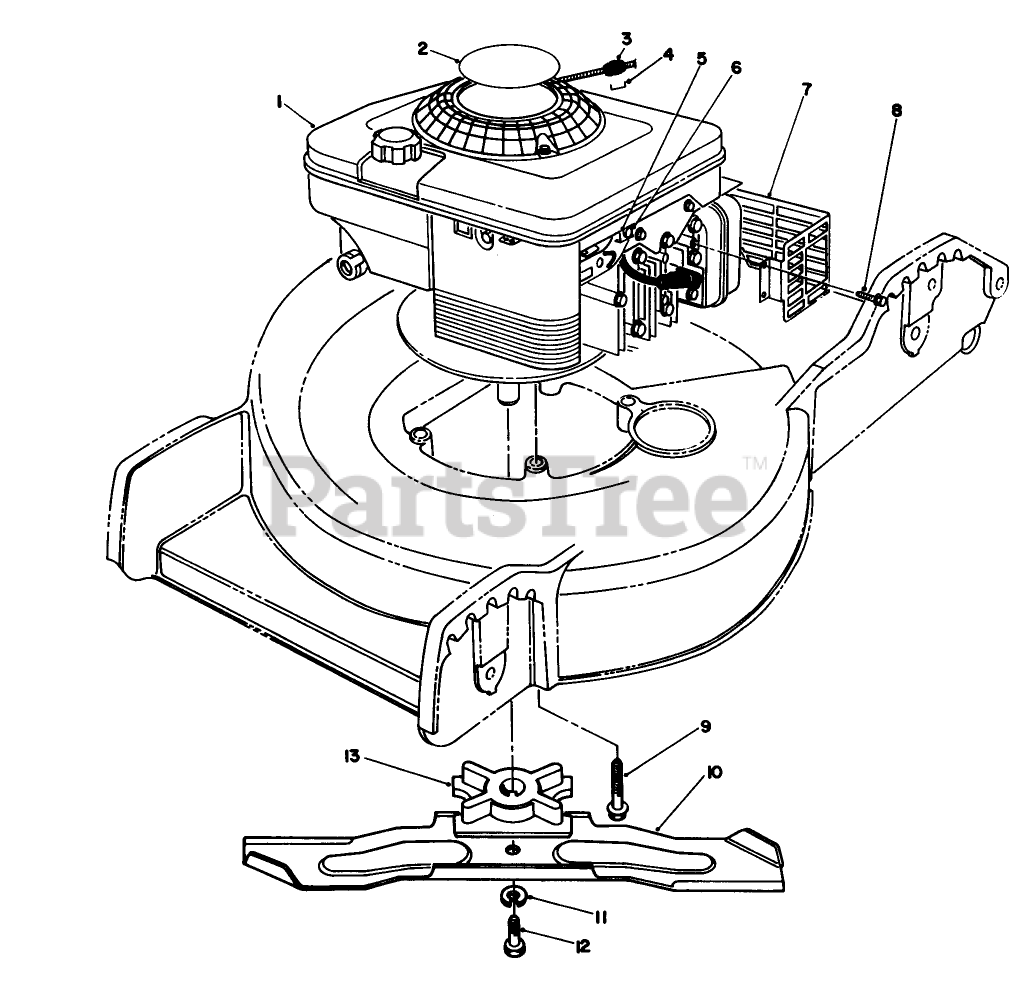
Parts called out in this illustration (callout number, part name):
1	Engine
3	Stop-Rope
4	Staple
5	CLAMP-CASING
11	WASHER-LOCK
12	SCREW-HH
13	BLADE RETAINER
